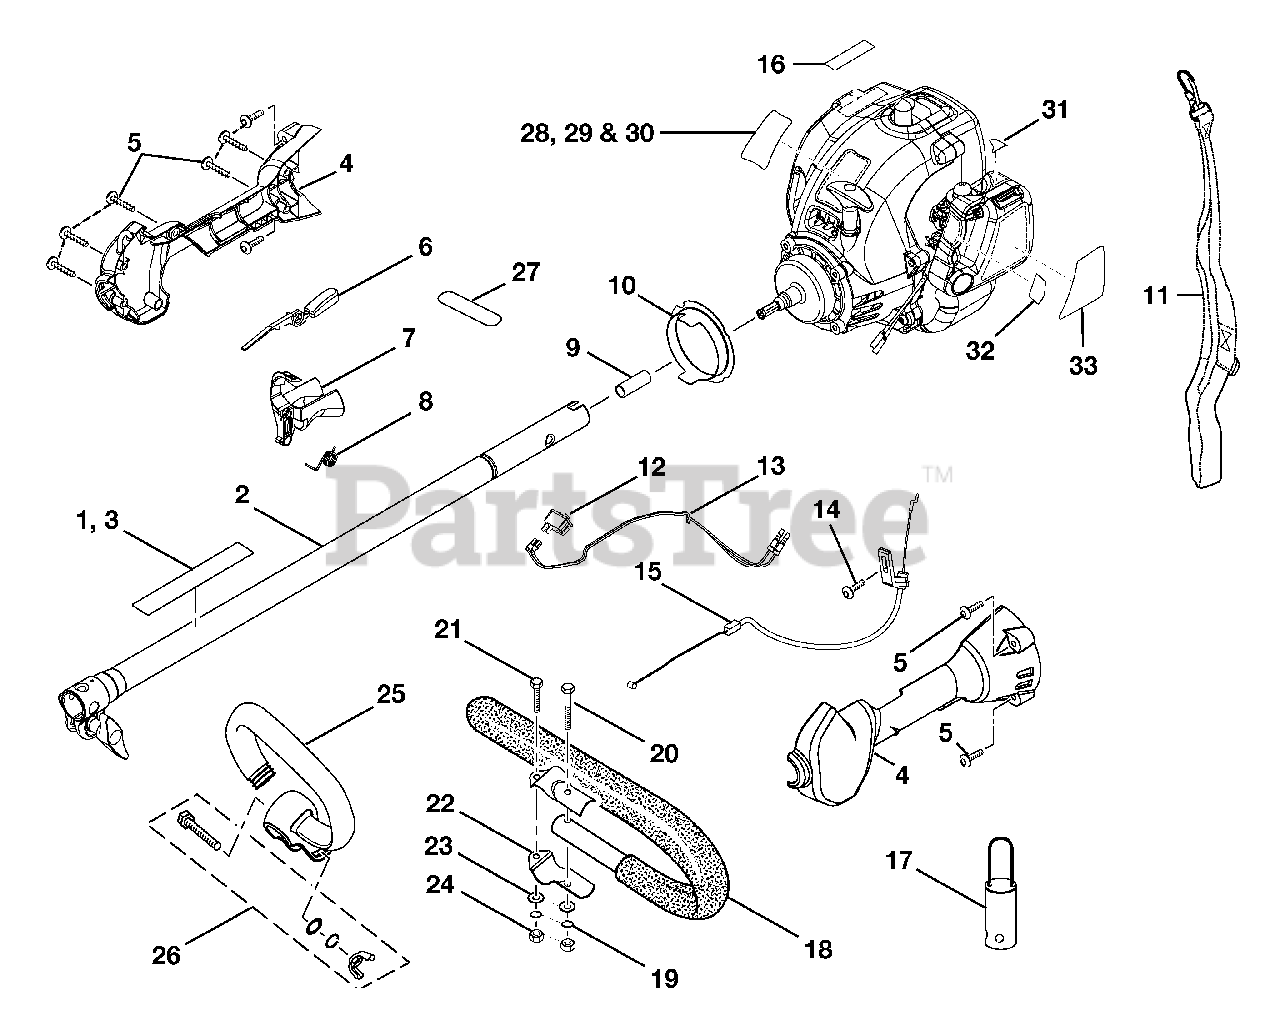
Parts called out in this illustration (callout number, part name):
1	WARNING DECAL (CS and SS)
2	BOOM ASSEMBLY (CS and SS)
3	WARNING DECAL (BC)
4	HANDLE ASSEMBLY (W/OUT SCREWS)
5	HANDLE SCREW
6	TRIGGER LOCK
9	SPRING
10	RING GUARD
11	SHOULDER STRAP (BC)
12	SWITCH (MOMENTARY CONTACT)
13	LEAD ASSEMBLY
15	THROTTLE CABLE
16	LOGO PLATE
17	HANGER CAP
18	"J" HANDLE AND GRIP (BC)
19	LOCK WASHER (BC)
20	HEX HEAD BOLT (BC)
21	SCREW (BC)
22	HANDLE BAR CLAMP (BC)
23	WASHER (BC)
24	HEX NUT (BC)
25	"D" HANDLE (CS and SS)
26	FASTENER PARTS KIT (CS and SS)
27	ON/OFF LABEL
28	MODEL LABEL (CS30)
29	MODEL LABEL (SS30)
30	MODEL LABEL (BC30)
31	PRIMER LABEL
32	CHOKE LABEL
33	STARTING LABEL
